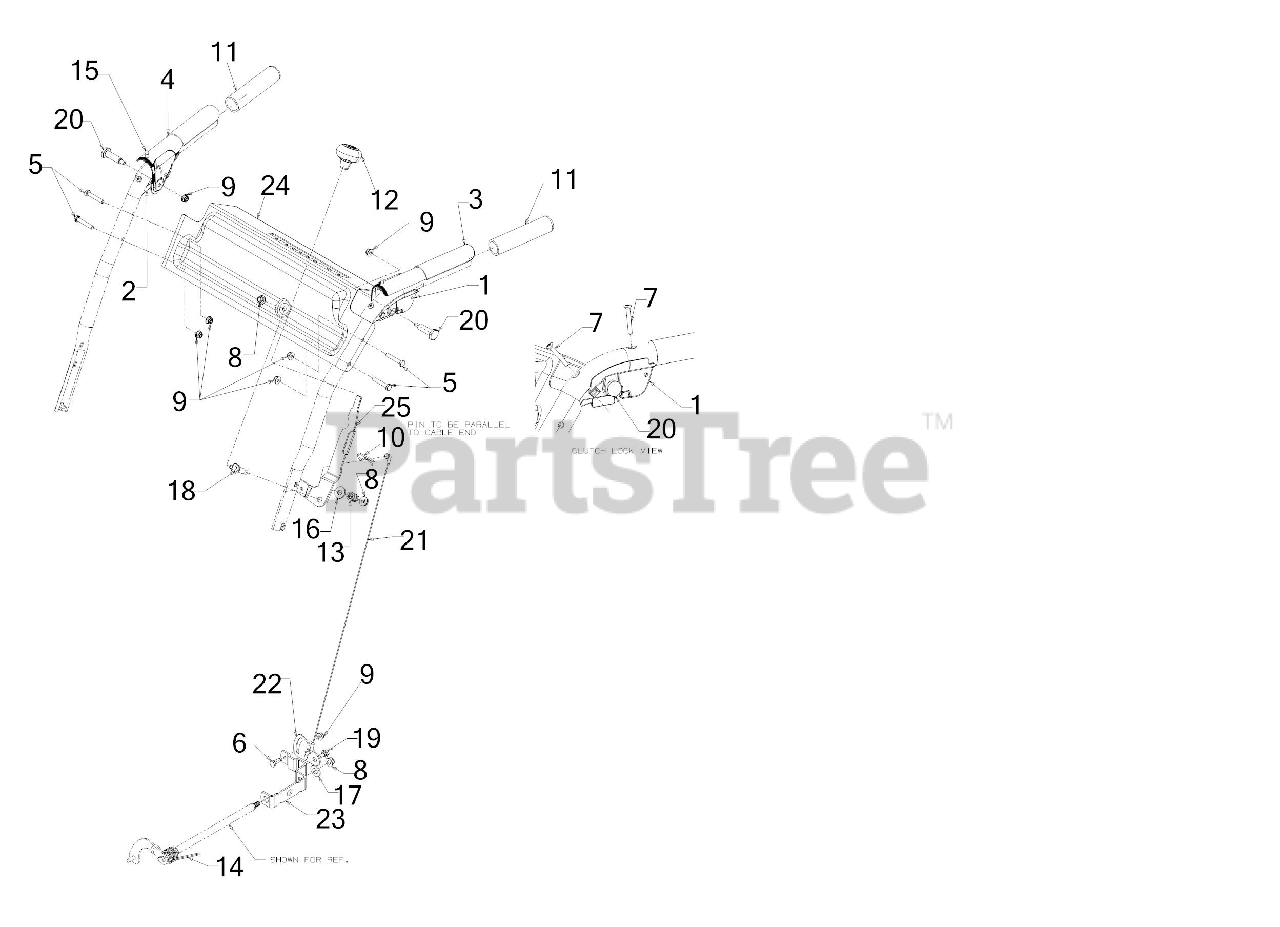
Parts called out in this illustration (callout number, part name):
1	CLUTCH LOCK HANDLE ASSEMBLY (LH)
2	CLUTCH LOCK HANDLE ASSEMBLY (RH)
3	HANDLE ASSEMBLY (LH)
4	HANDLE ASSEMBLY (RH)
5	SCREW 1/4-20 x 1.50 GR.5
6	SCREW 1/4-20 x .620 GR5
7	SCREW #10-24 x 1.375
8	FLANGE LOCK NUT 5/16-18
9	FLANGE LOCK NUT
10	INTERNAL COTTER PIN
12	SHIFT KNOB
13	COMPRESSION SPRING
14	TORSION SPRING
15	RUBBER BUMPER
16	FLAT WASHER .385X.870X.090
17	FLAT WASHER
18	SHOULDER BOLT
19	SHOULDER SCREW
20	SHOULDER SCREW .437 x 1.345 1/4-20
21	SPEED SELECTOR CABLE (STEEL)
22	PIVOT BRACKET
23	SHIFT SPEED BRACKET
